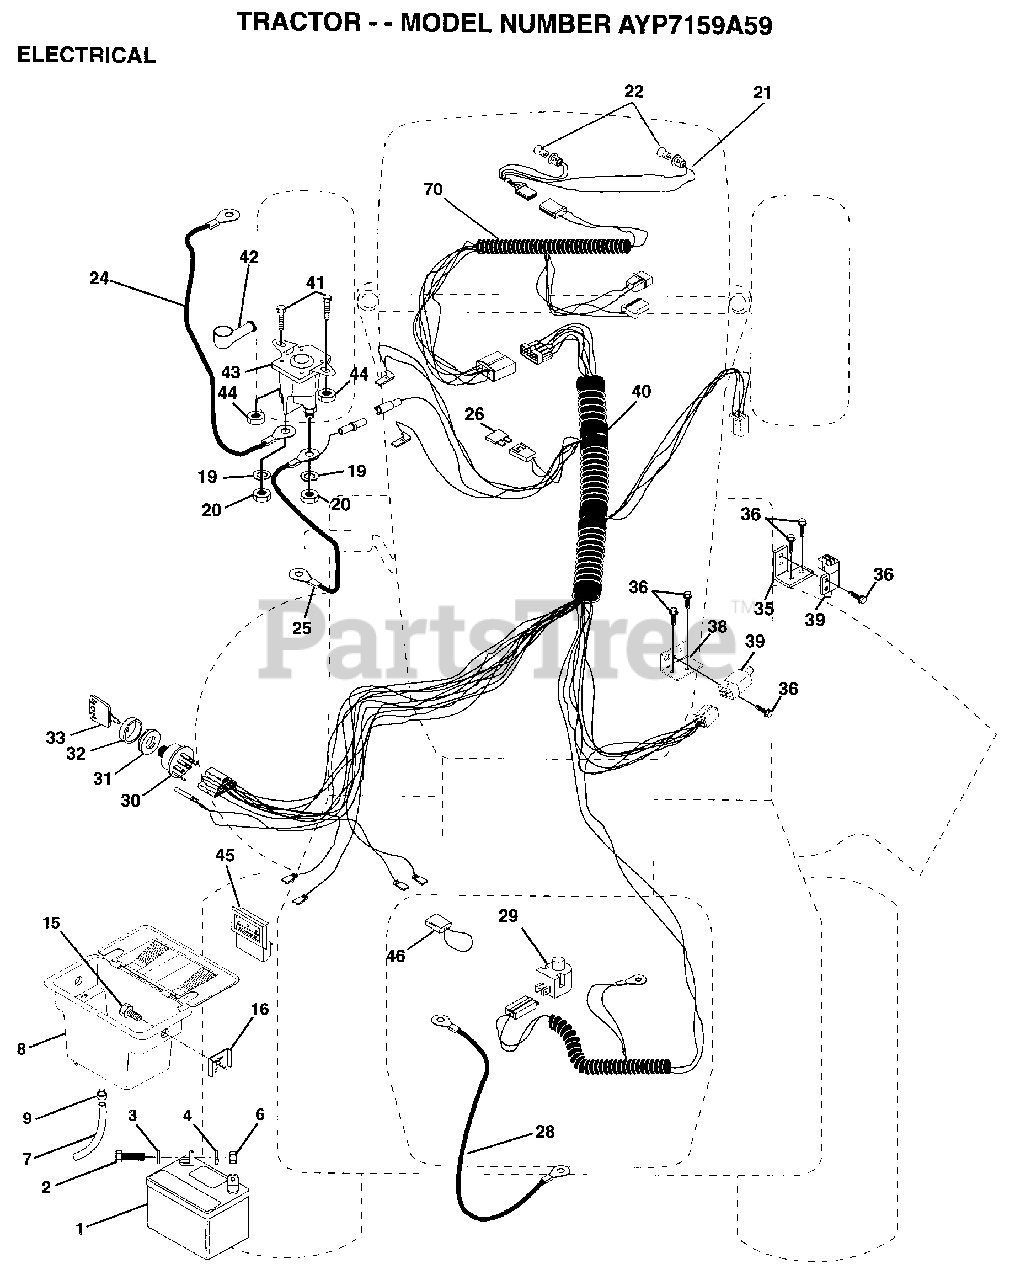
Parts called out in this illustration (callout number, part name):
2	BOLT LT
3	WASHER
4	LOCKWASHER
7	TUBE T
9	HOSE CLAMP T
15	SCREW.CAP.HEX.NYL
16	NUT.CLIP.FASTNER
20	NUT
21	"HARNESS,LIGHT SOC"
22	HEADLAMP BULB
24	"CABLE T, BATTERY"
25	CABLE.BTRY.6GA.RD
26	FUSE HYT
28	CABLE T
29	SWITCH SEAT
30	SWITCH IGN 4POS
31	NUT IGNITION
32	COVER KEY SWITCH
33	KEY
35	BRACKET LT
36	SCREW
38	BRACKET SWITCH IN
39	SWITCH INTERLOCKT
41	BOLT.HX.1/4-20
44	NUT
46	PROTECTION LOOP
70	HARNESS ENGINE
